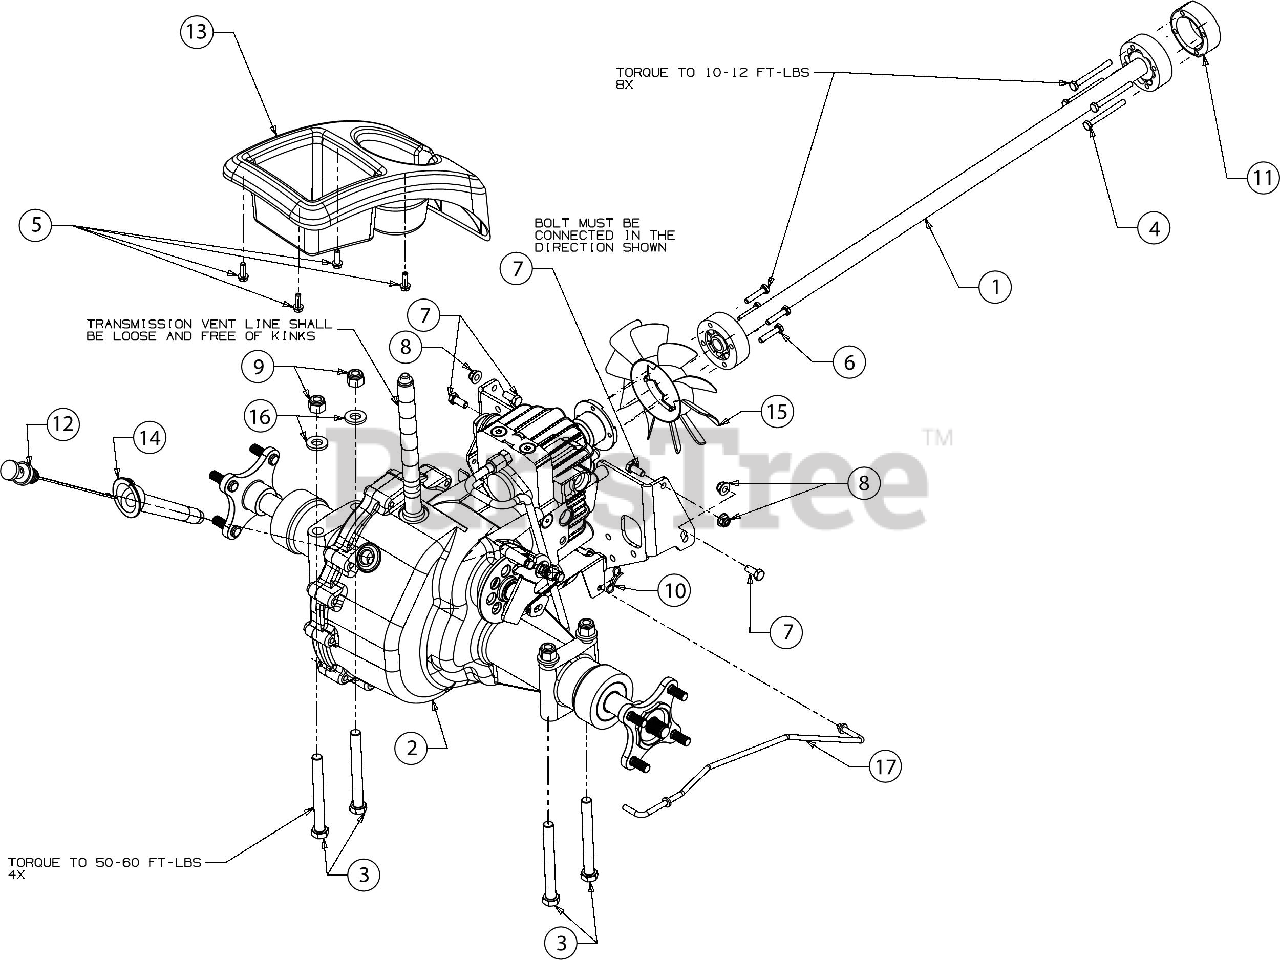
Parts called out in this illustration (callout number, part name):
1	DRIVE SHAFT ASSEMBLY 30.55
2	TRANSMISSION
3	SCREW 1/2-20 x 4.50 GR5
4	SCREW 1/4-20 x 2.50 GR5
5	SCREW 1/4-15 x .750
6	SCREW 1/4-20 x 1.25 GR5
7	SCREW 5/16-18 x .75 GR5
8	FLANGE LOCK NUT 5/16-18
9	HEX NUT CENTER
10	BOW TIE COTTER PIN 1/4-5/16
11	DRIVE SHAFT ADAPTER
12	TRANSMISSION DIPSTICK
13	FENDER COVER-CUP HOLDER (LH)
14	DIPSTICK HOLDER
15	10 BLADE COOLING FAN
16	FLAT WASHER .531X1.060X.134
17	HYDRO PUMP RELEASE ROD
